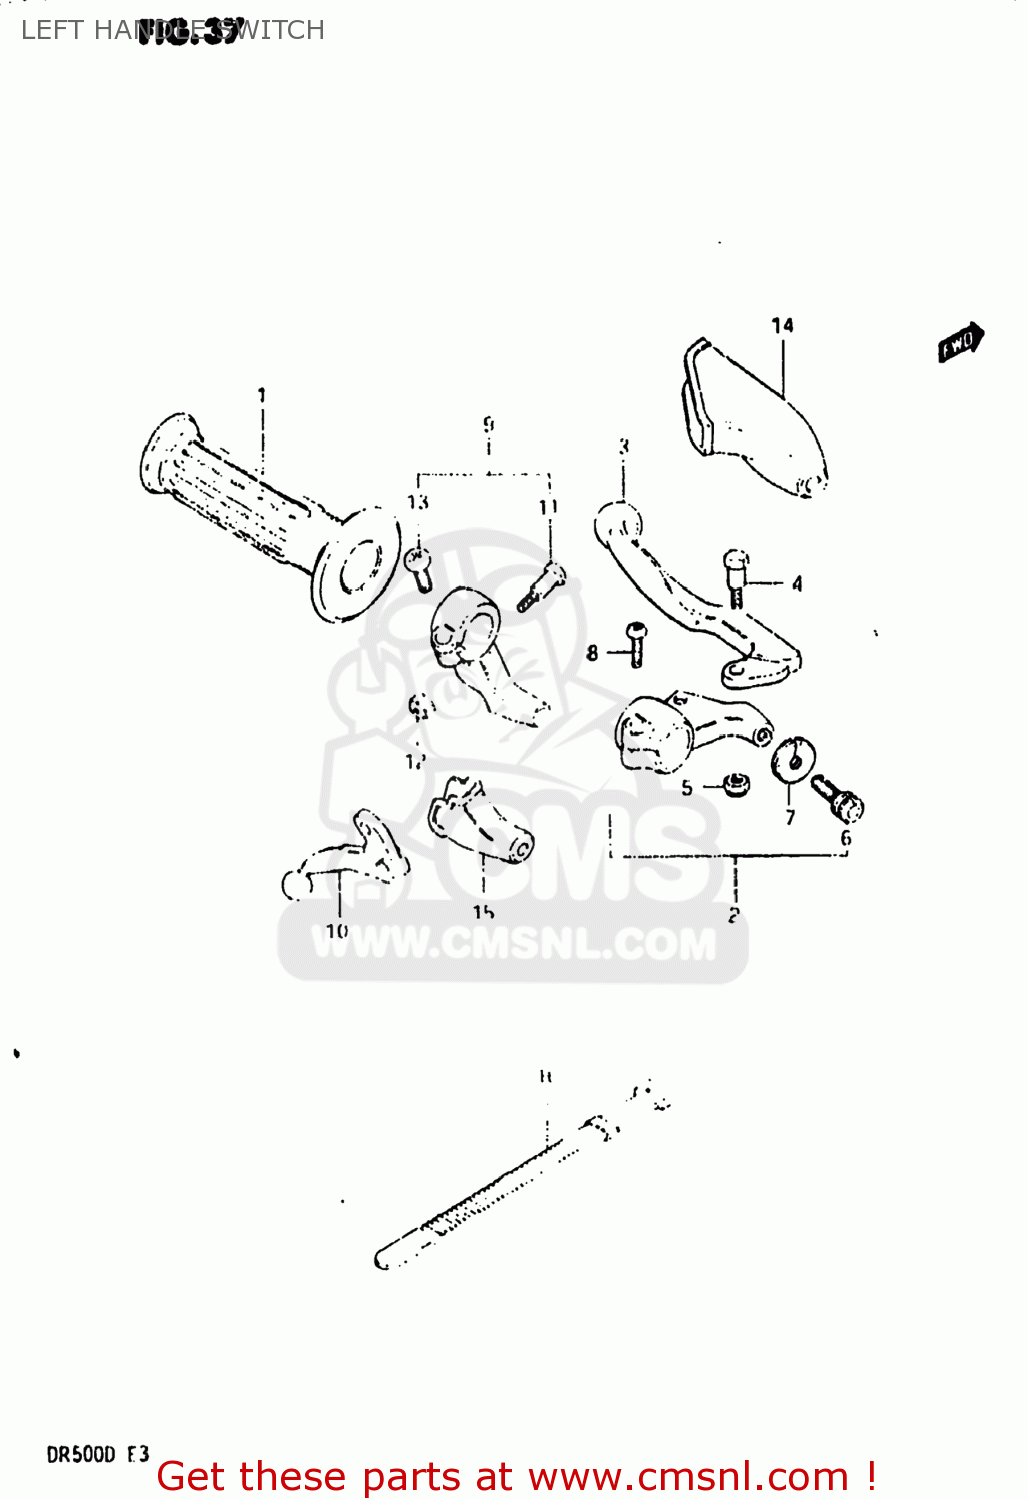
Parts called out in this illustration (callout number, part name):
1	GRIP,L
2	LEVER ASSEMBLY,CLUTCH
3	LEVER,CLUTCH
4	BOLT,LEVER
5	NUT 6MM
6	ADJUSTER,CABLE
7	NUT,CABLE ADJUSTER
8	SCREW
9	LEVER ASSEMBLY,DECOMPRESSION
10	LEVER,DECOMP
11	BOLT,LEVER
12	NUT
13	SCREW
14	COVER,CLUTCH LEVER
15	COVER,DECOMP LEVER DUST
16	CLAMP
